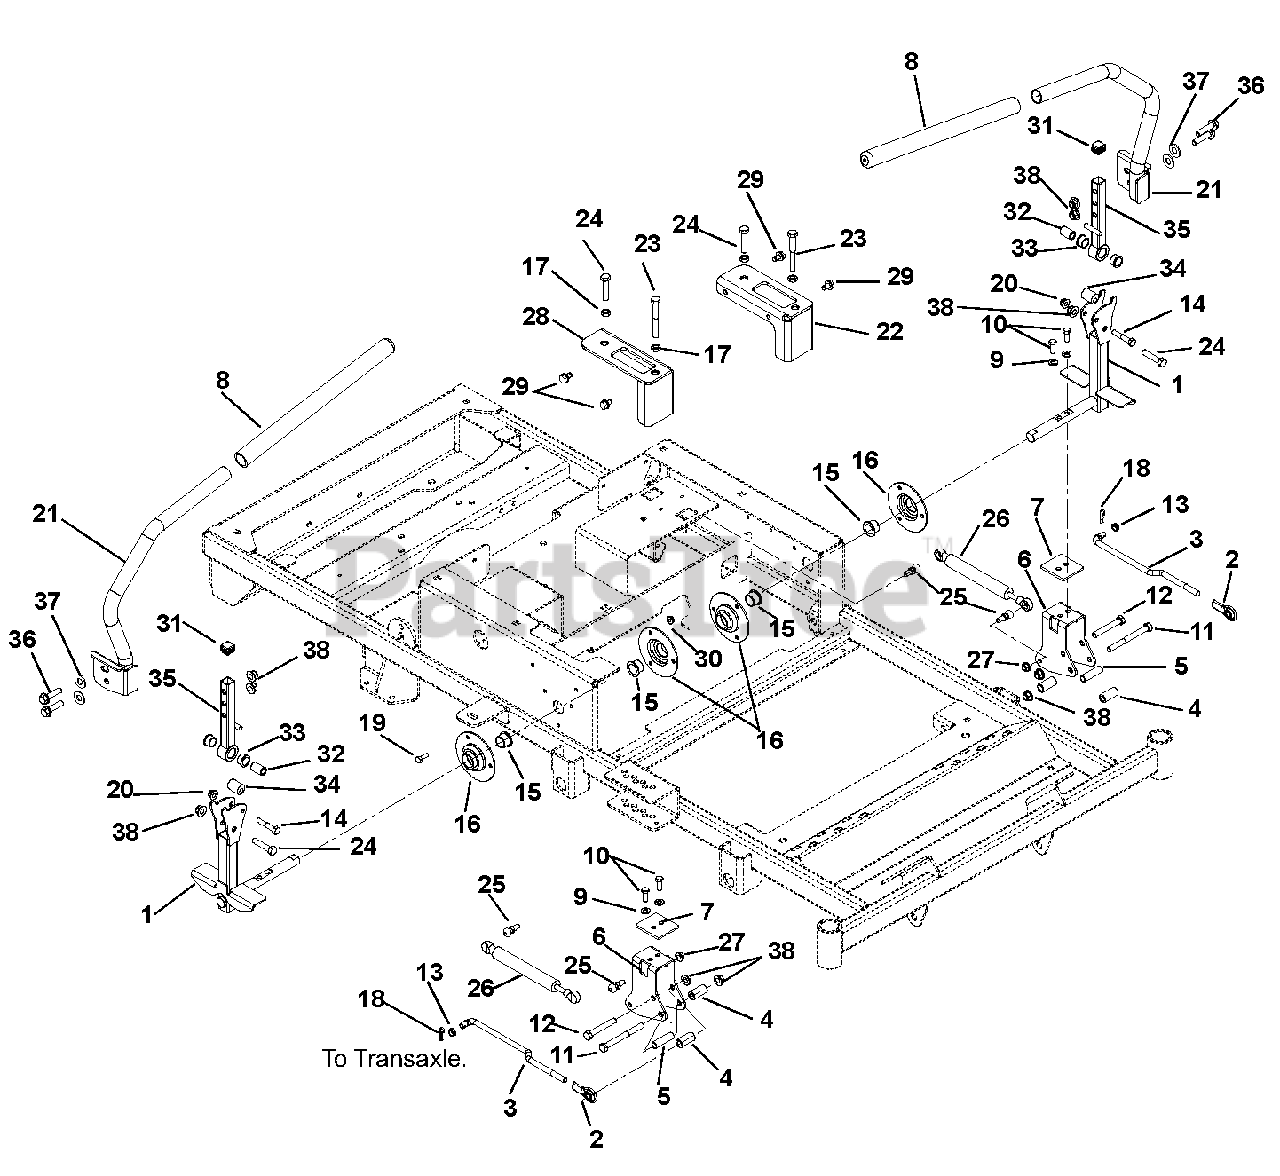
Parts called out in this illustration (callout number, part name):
1	Weldment, Control Arm
2	Rod End, .38 Right Hand
3	Link, Transmission
4	Bushing, Spacer .390 x .625 x 1.25 Promaster
5	Spacer, Steering
6	Bracket, Steering
7	Plate, Steering Reinforcing
8	Grip, Handlebar 15" Foam
9	Washer, Locking .31 x .078
10	Bolt, Hex .31-18 x 1.00 Grade 8
11	Bolt, Hex .38-16 x 3.75 Grade 5
12	Bolt, Hex .38-16 x 2.50 Grade 5
13	Bushing, Polyliner 322-C
14	Bolt, Hex .31-18 x 1.75 Grade 5
15	Bushing, Flange .750 x 1.000 x .625 x 1.250
16	Bearing Flange
17	Nut, Hex Jam .375-16
18	Pin, Hair Internal .08 x .18 x 1.18
19	Bolt, Hex .25-20 x .75 Grade 5
20	Nut, .31-18 Nyloc Flange
21	Weldment, Steering Handle Right Hand
22	Bracket, Left Hand Speed Control
23	Bolt, Hex .38-16 x 3.00 Grade 5
24	Bolt, Hex .375-16 x 1.750 Full Thread
25	Stud, Ball
26	Damper, Control
27	Nut, Locking Top Flange .31-18
28	Bracket, Right Hand Speed Control
29	Screw, Tapping .31-18 x .50 Hex Washer Head
30	Nut, Locking Top Flange .25-20
31	Cap Plug, Square .75-14-20 Ribbed
32	Spacer, .375 x .625 x .970 (PM)
33	Bushing, Flange, .625 x .750 x .450 x .875
34	Bushing, Eccentric .31 x .75 x .97
35	Weldment, Upper Control Arm
36	Bolt, Serrated Hex Flange Washer Head .375-16 x 1.25
37	Washer, Flat Steel .406 x .812 x .065
38	Nut, Locking Center Jam .375-16
